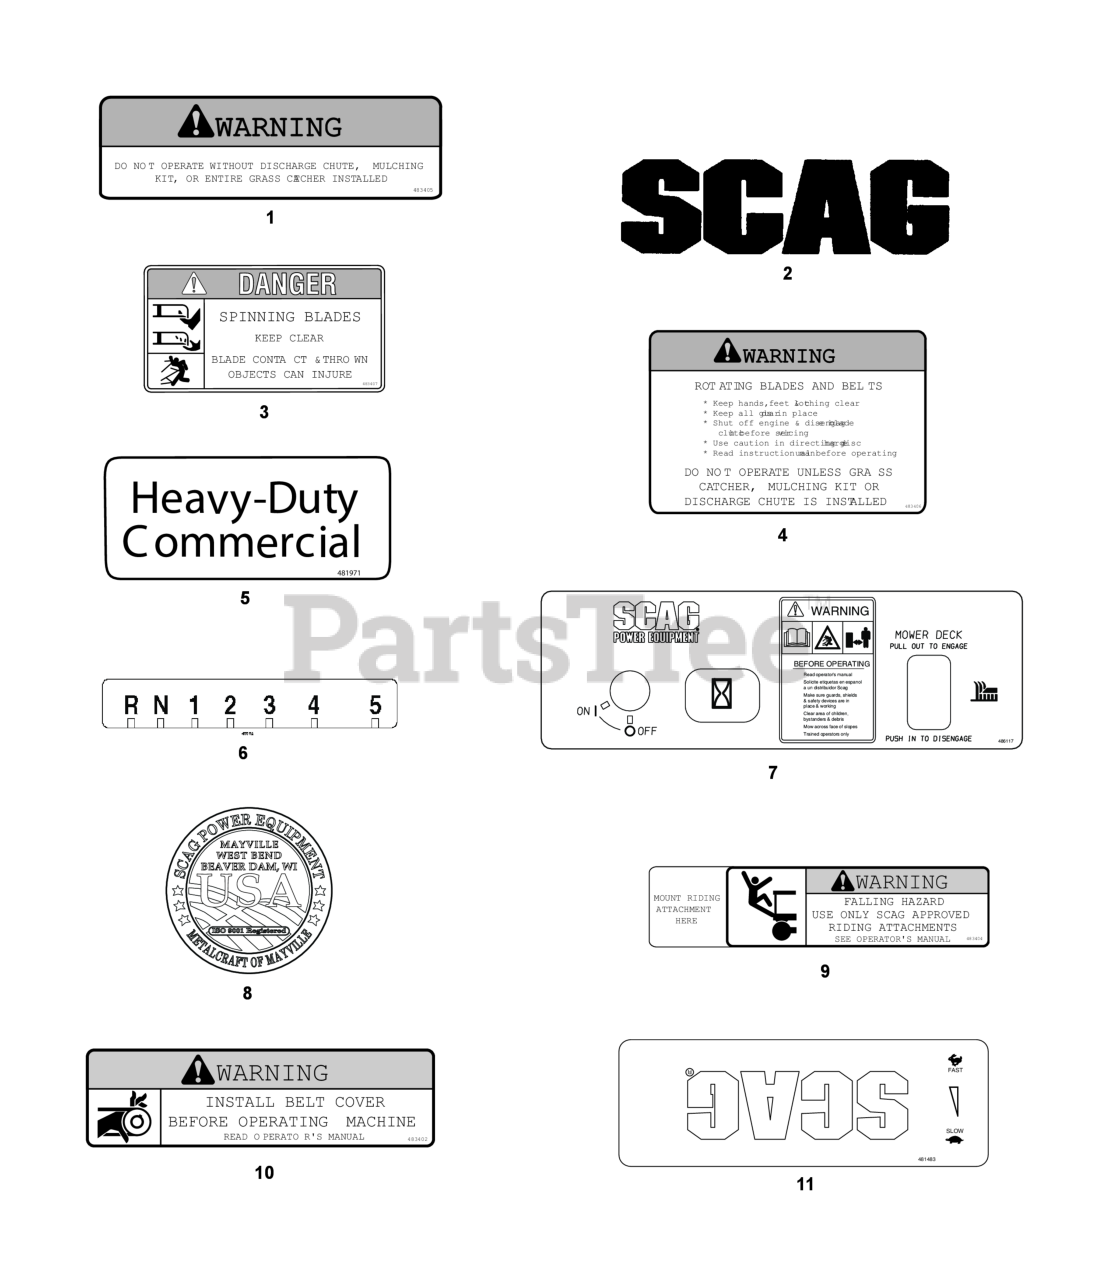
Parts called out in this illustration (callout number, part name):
1	Decal, Warning-Discharge
2	Decal, Scag Logo ( Cutter Deck)
3	Decal, Danger-Spinning Blades
4	Decal, Warning - Rotating Blades
5	Decal, Heavy Duty Commercial
6	Decal, Shift Index
7	Decal, Instrument Panel - Rear
8	Decal, Metalcraft - USA
9	Decal, Sulky Attachment
10	Decal, Warning - Belt Cover
11	Decal, Instrument Panel - Front
